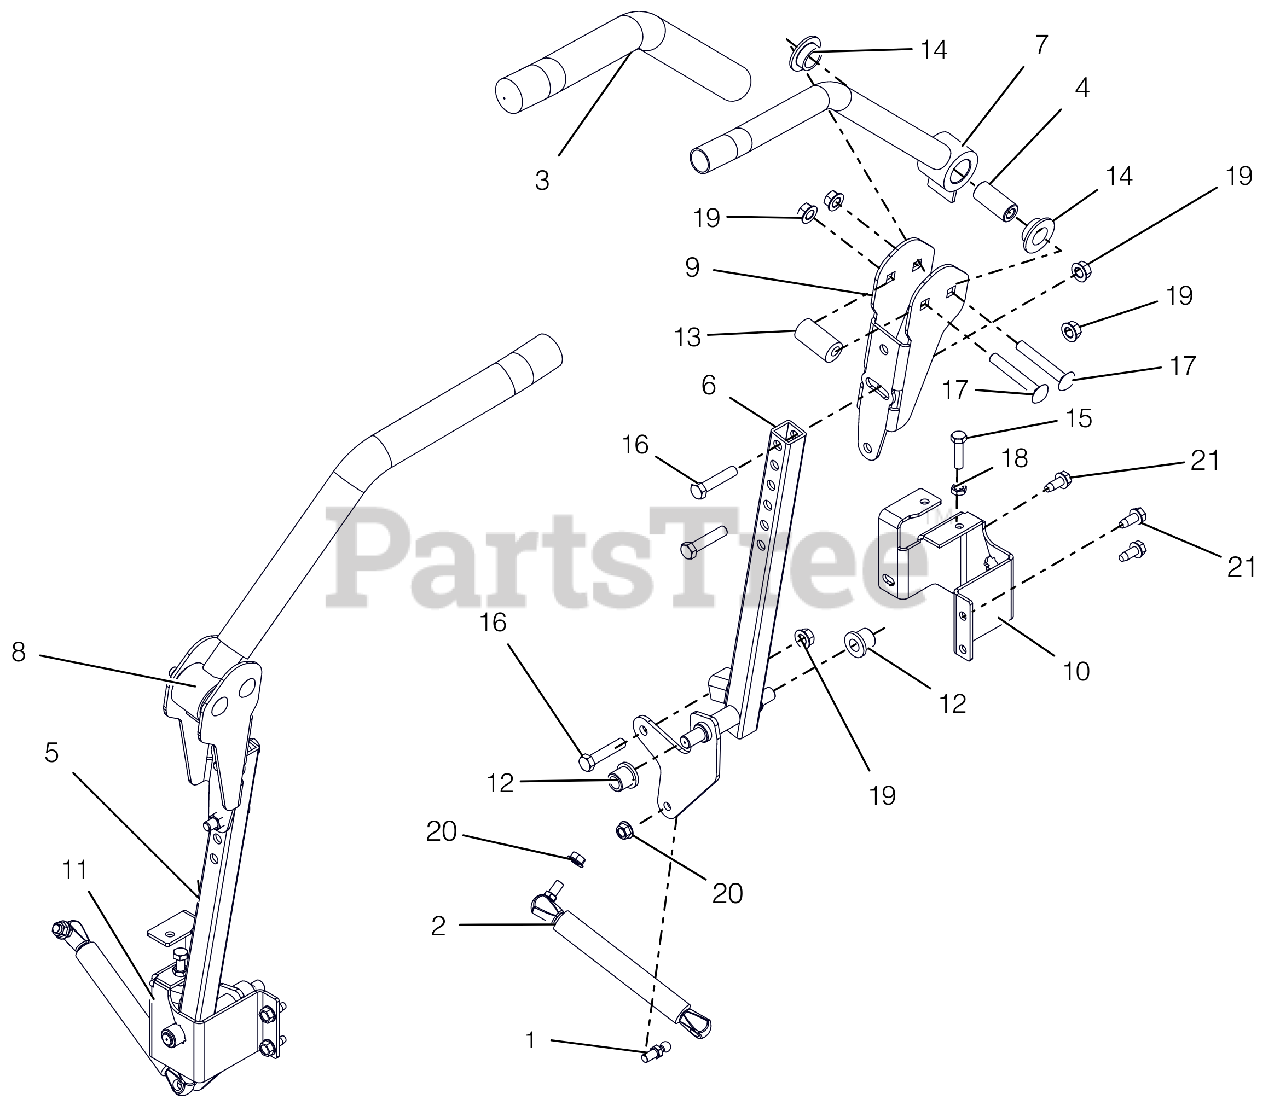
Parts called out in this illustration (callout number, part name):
1	STUD- BALL
2	DAMPER
3	GRIP, HANDLEBAR
4	SPACER, STEERING ARM
5	WLDMT, STEERING RH
6	WLDMT, STEERING LH
7	WLDMT, CONTROL HANDLE- BLK
8	WLDMT, CONTROL HANDLE- BLK
9	ADJ UPPER CONTROL ARM BRKT-BLK
10	BRKT, STEERING ARM MOUNT -LH
11	BRKT, STEERING ARM MOUNT -RH
12	BHSG-FLG .500X.750X.750X.125
13	BSHG, ECCENTRIC.406X.875X1.625
14	BSHG-FLG .762X1.48X.44 NYL
15	@BLT-HEX .31-18X1.25 GR5 YWZC
16	@BLT-HEX .38-16X1.75 GR5 YWZC
17	BLT-RDHDSQSHK, 38-16X2.50 G5YZ
18	NUT- JAM .312-18 YWZC
19	@NUT-LK-TOP-FLG .38-16 YWZC
20	@NUT-LK-TOP-FLG .31-18 YWZC
21	@SCR-TAP .31-18X.75 HWH TR YWZ
